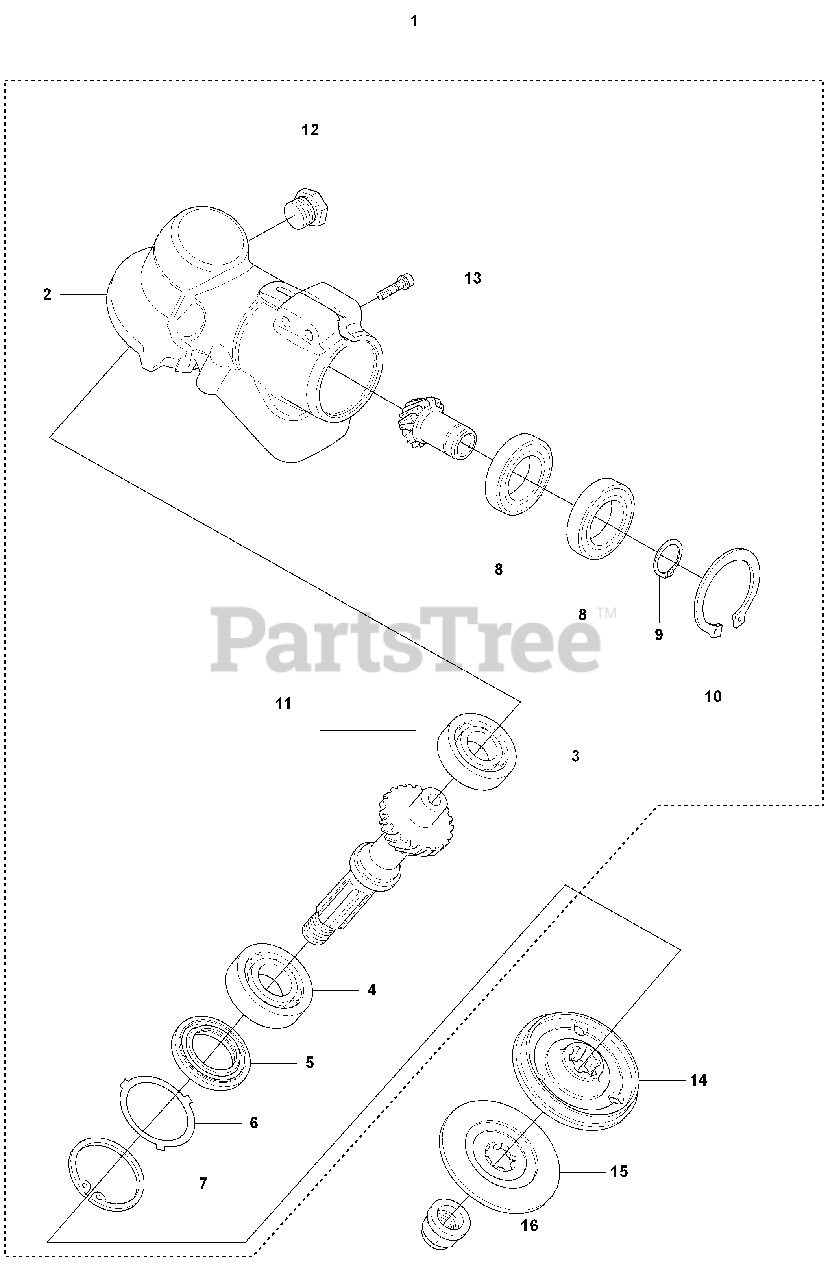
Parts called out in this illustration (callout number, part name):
2	%GEAR HOUSING
3	BALL BEARING
4	BALL BEARING
7	RETAINING RING SGH 35
8	BALL BEARING
9	RETAINING RING SGA 15
10	RETAINING RING
11	BEVEL GEAR
15	SUPPORT FLANGE
16	BLADE NUT
